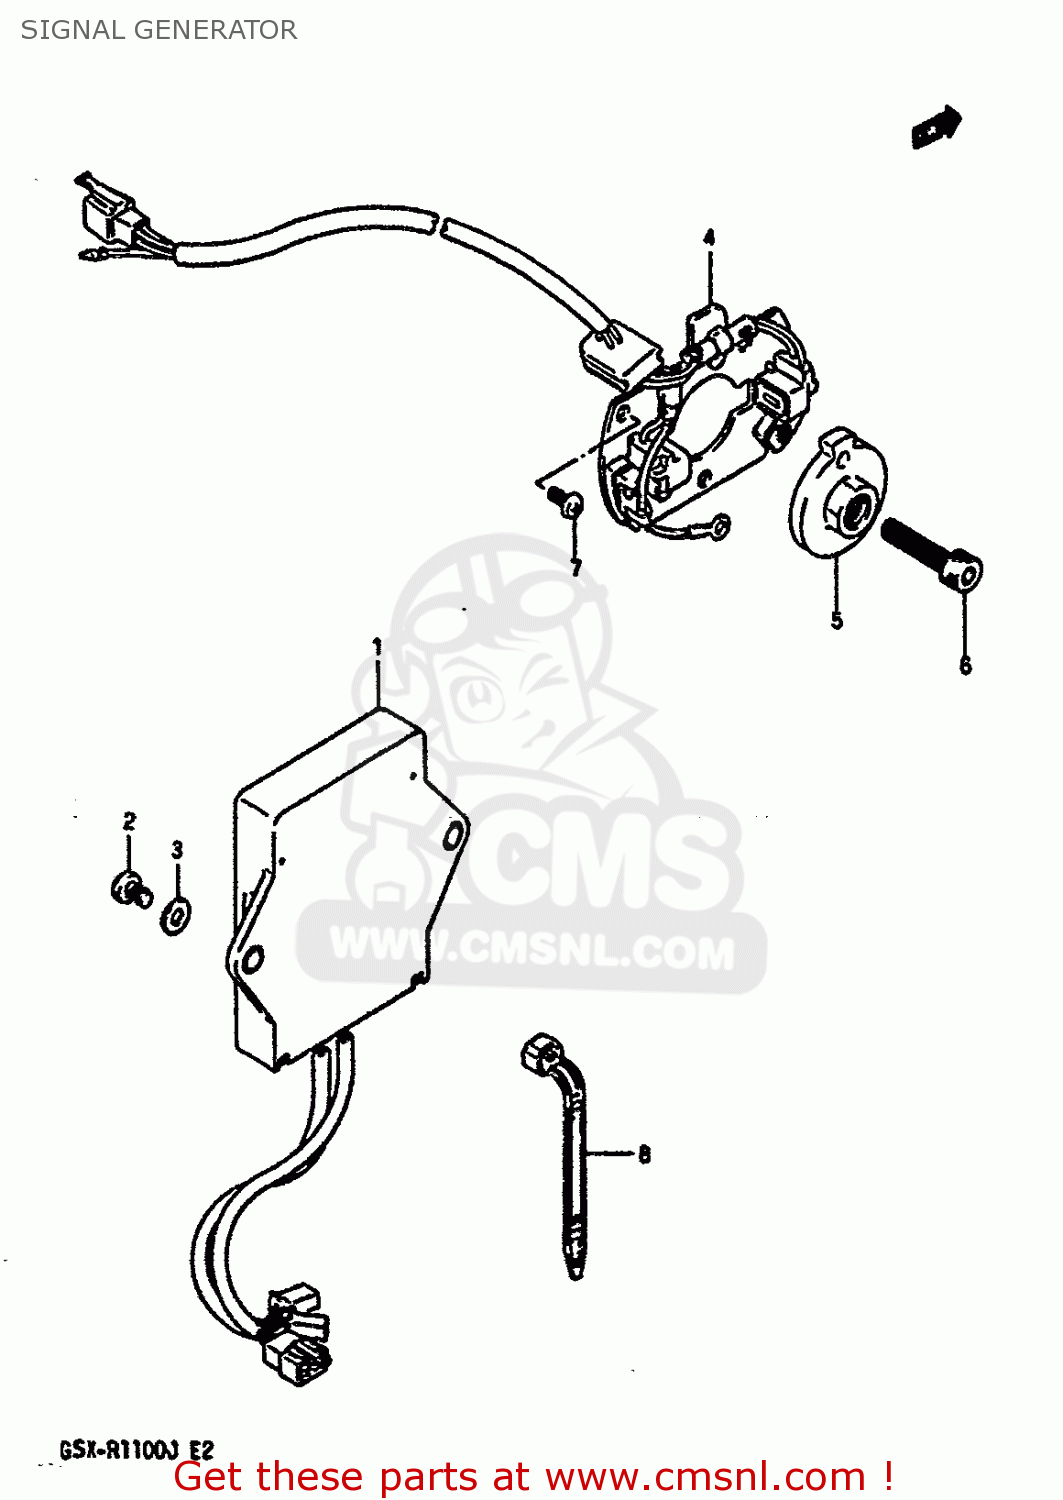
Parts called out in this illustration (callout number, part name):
1	IGNITER UNIT
2	SCREW
3	WASHER, LOWER
4	GENERATOR ASSEMBLY,SIGNAL
5	ROTOR COMP,SIGNAL
6	BOLT
7	SCREW
8	CLAMP(L:125)
